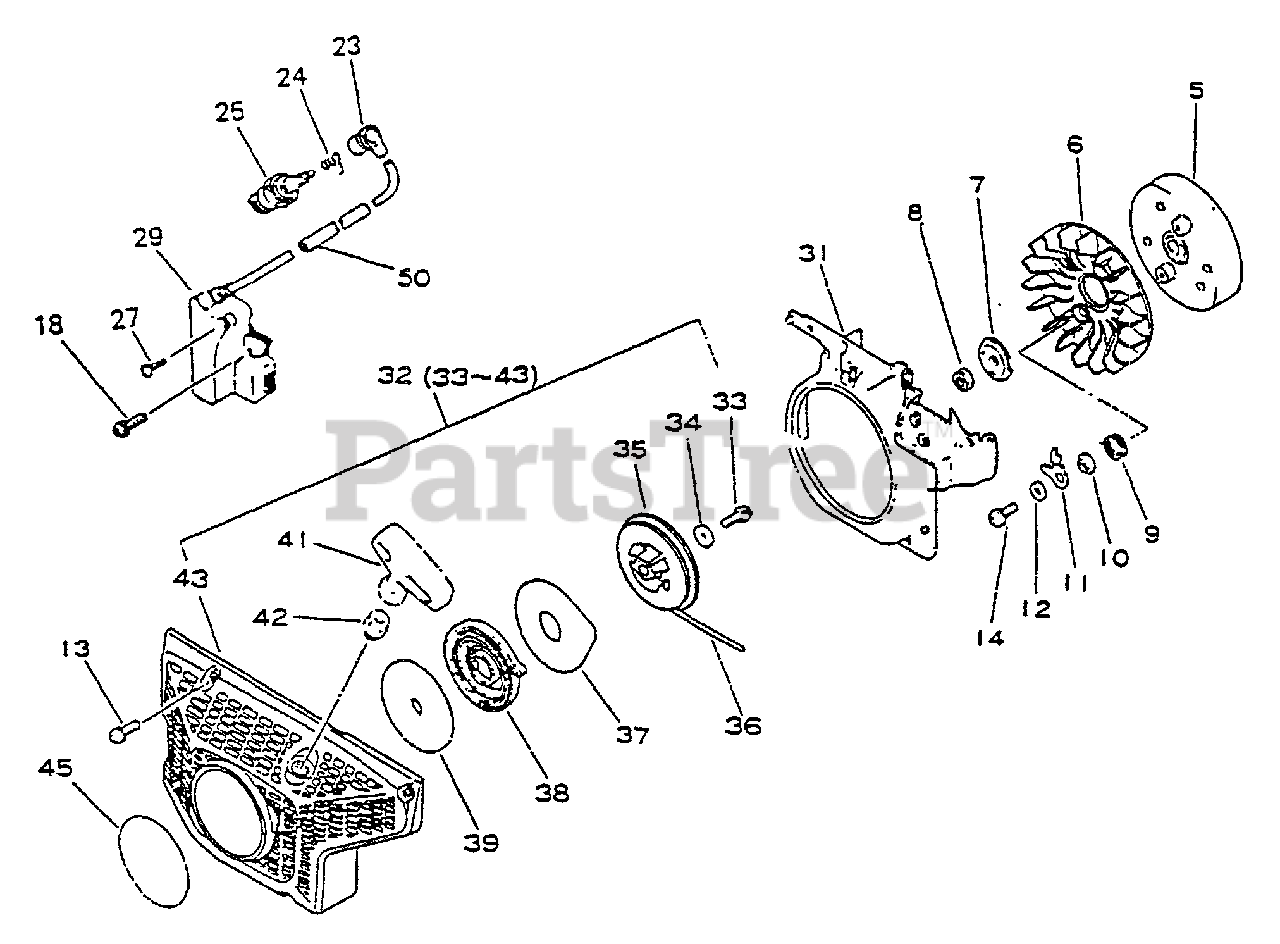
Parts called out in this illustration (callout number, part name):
5	FLYWHEEL
7	WASHER - CUP
9	SPRING, RETURN
11	PAWL, STARTER
12	WASHER - 5
13	SCREW - 5X20
14	SCREW - 5X14
18	SCREW - 4X20
23	CAP, SPARK PLUG
24	TERMINAL, SPARK PLUG CAP
25	SPARK PLUG -- BPM-7A
27	SCREW - 4X8
29	COIL, IGNITION
31	SHIELD, FAN
32	STARTER ASSY
33	SCREW - 5X14
34	WASHER - 5
35	REEL, ROPE
36	ROPE, STARTER - 4X950
37	PLATE, STARTER
38	SPRING, REWIND
39	PLATE, STARTER
41	GRIP, STARTER
42	GUIDE, ROPE
43	CASE, STARTER
45	LABEL - ECHO
50	TUBE
